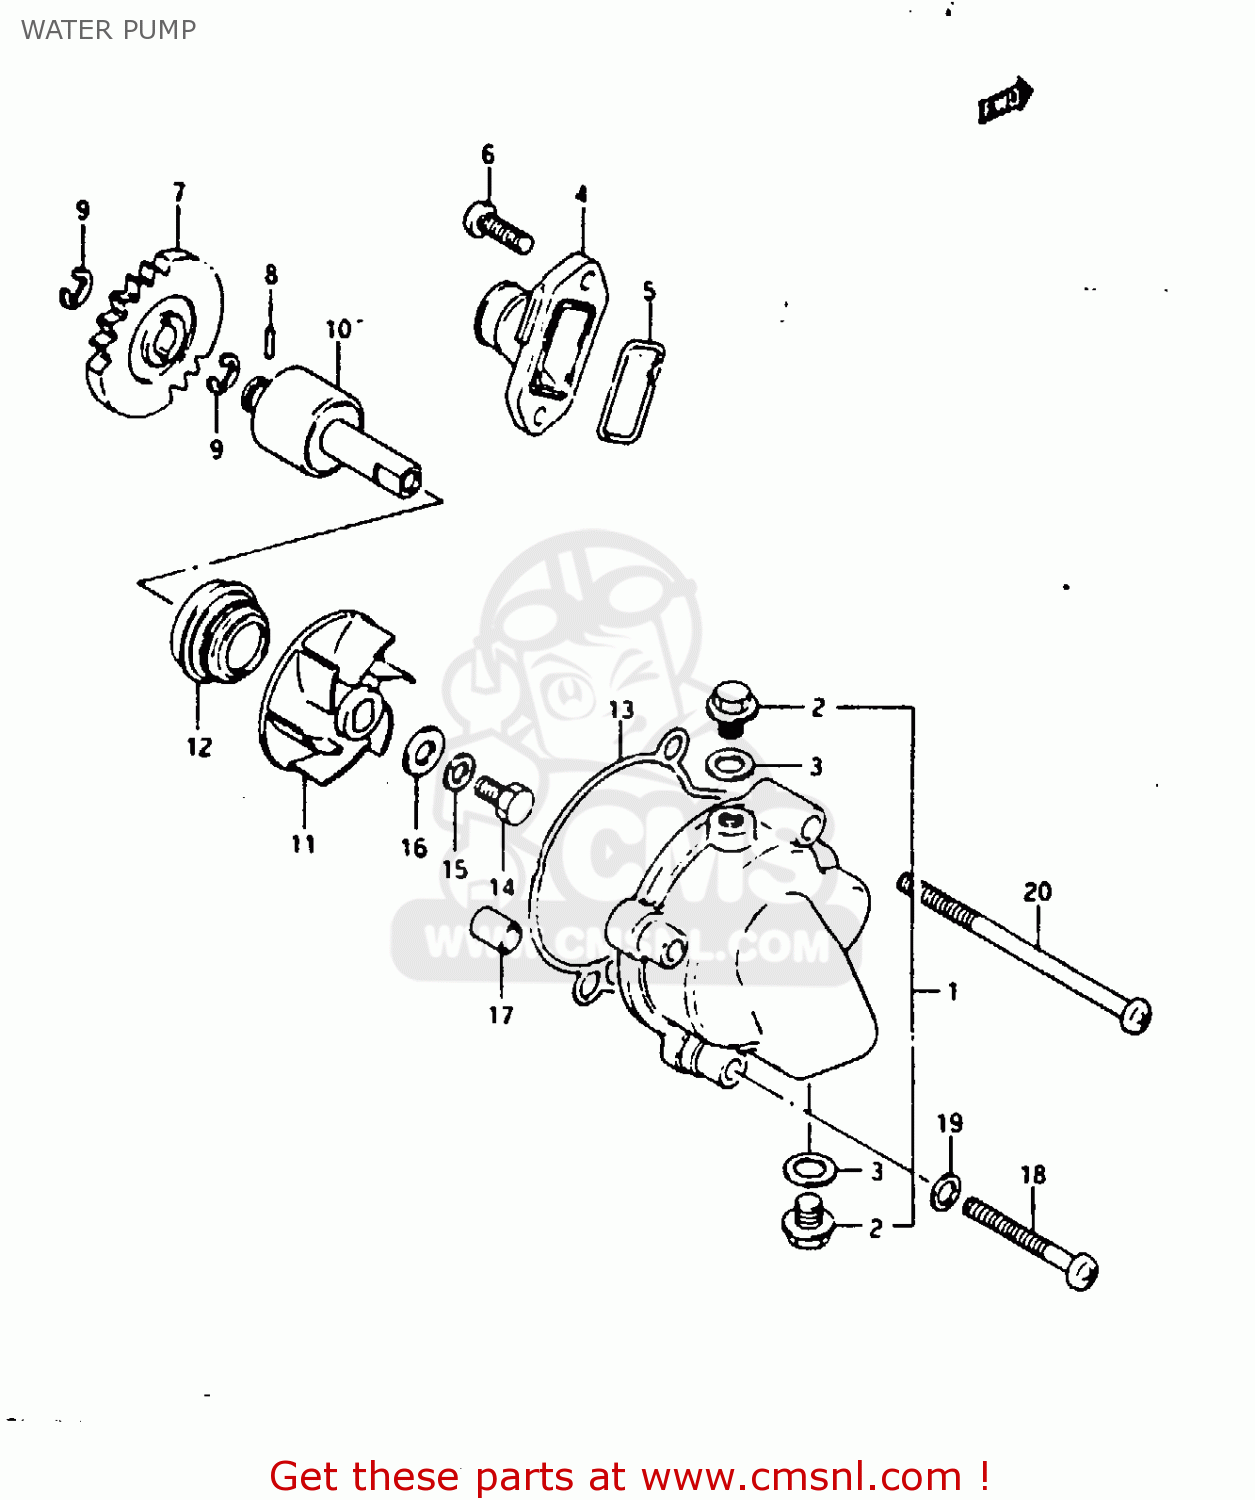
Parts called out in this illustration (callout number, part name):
1	CASE, WATER PUMP
2	BOLT,DRAIN
3	GASKET 8.2X14X1 (NAS)
4	CONNECTOR, INLET
5	O RING,WATER PUMP CONNECTOR
6	SCREW
7	GEAR, DRIVEN (NT:25)
8	PIN(5.1X18.8)
9	E RING
10	SHAFT, WATER PUMP
11	IMPELLER,WATER PUMP
12	SEAL,MECHANICAL
13	O RING,WATER PUMP CASE
14	BOLT(6X13)
15	WASHER
16	GASKET (NAS)
17	PIN
18	SCREW
19	WASHER
20	SCREW
